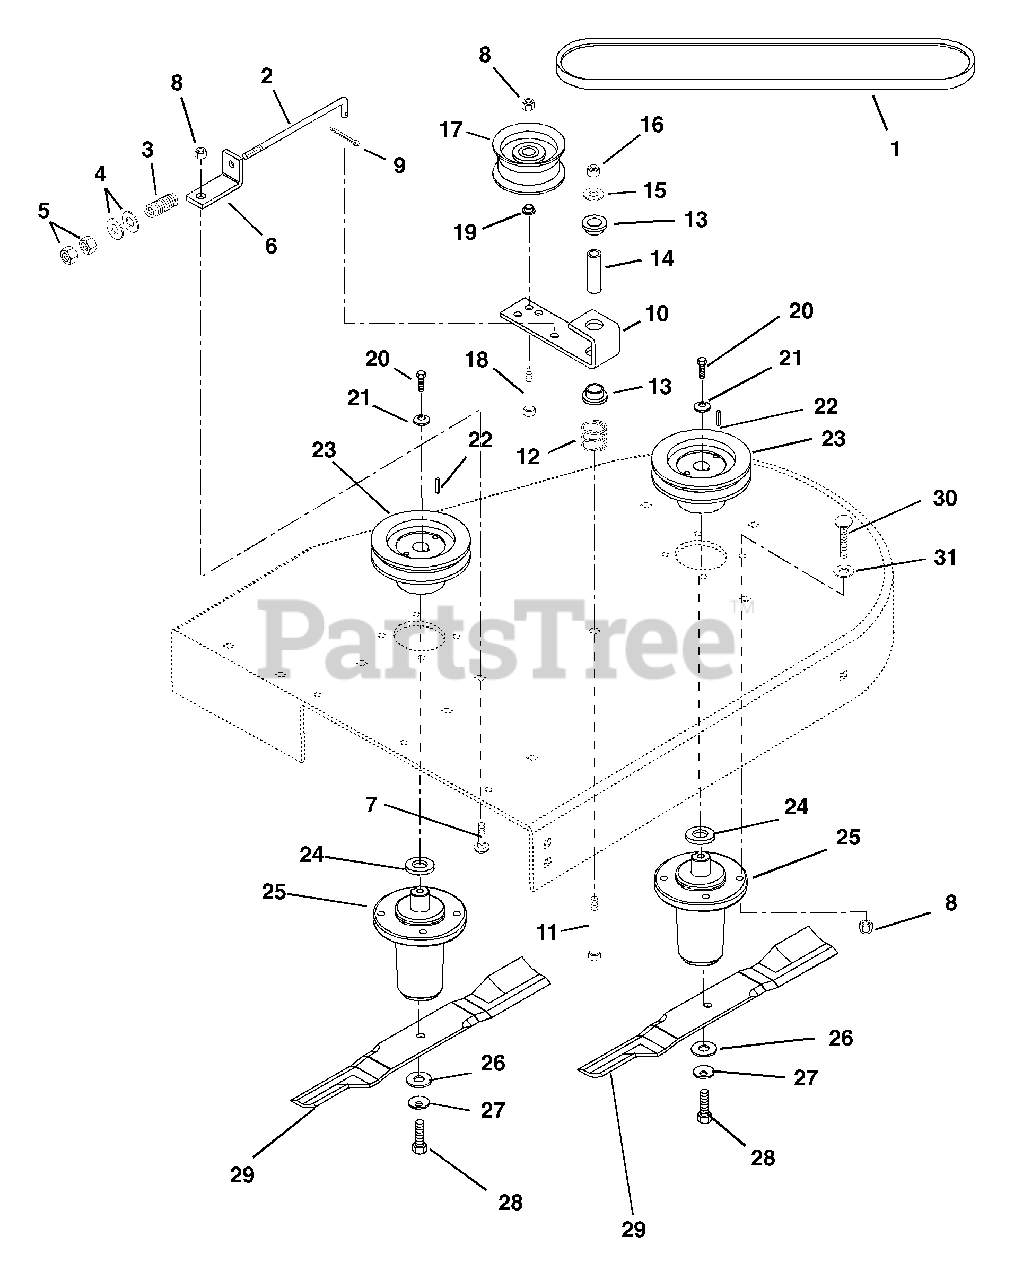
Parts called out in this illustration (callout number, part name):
1	V-Belt, Wrapped, Pro 150/50"
1	V-Belt Pro 250 36" Mower
2	Rod, Idler 72" Mower
3	Spring-Compression .125 x .78 x 1.00
4	Washer-Flat-Steel .406 x .812 x .065
5	Nut-Hex .375-24 Grade 2
6	Bracket, Belt Tensioner
7	Bolt-Round Head Square Neck .38-16 x 1.0
8	Nut-Locking-Nylon .375-16 Grade 2
9	Pin-Cotter .09 x .75
10	Arm, Idler Pivot
11	Bolt-Hex .50-13 x 3.25 Grade 5
12	Spring-Compression .085 x .80 x 1.00
13	Bushing-Flange .762 x 1.0 x .580 x 1.48
14	Bushing, Steel .560 x .750 x 2.44
15	Washer-Flat-Steel .531 x 1.250 x .100
16	Nut-Locking .50-13
17	Idler-Flat 4-6.87 x .38
18	Bolt-Hex .38-16 x 2.25 Grade 5
19	Bushing-Flange .406 x .88 x .270 x .140
20	Bolt-Hex .38-16 x 1.00 Grade 8
21	Washer, Cupped, Serrated .375
22	Key-Square .25 x 1.00 x .25 SAE 860 or SAE 1035
23	Weldment, Pulley-V 4.75 x 1.004 with Key
24	Slinger, Dust
25	Spindle, Maintenance Free Assembly
26	Washer, Flat .64 x 1.81 x .25
27	Washer, Bellville .63 x 1.63 x .14
28	Bolt, Blade
29	Blade, Mower-Tungsten Carbide
30	Bolt-Hex .38-16 x 1.25 Grade 5
31	Washer-Flat-Steel .500 x 1.250 x .083
